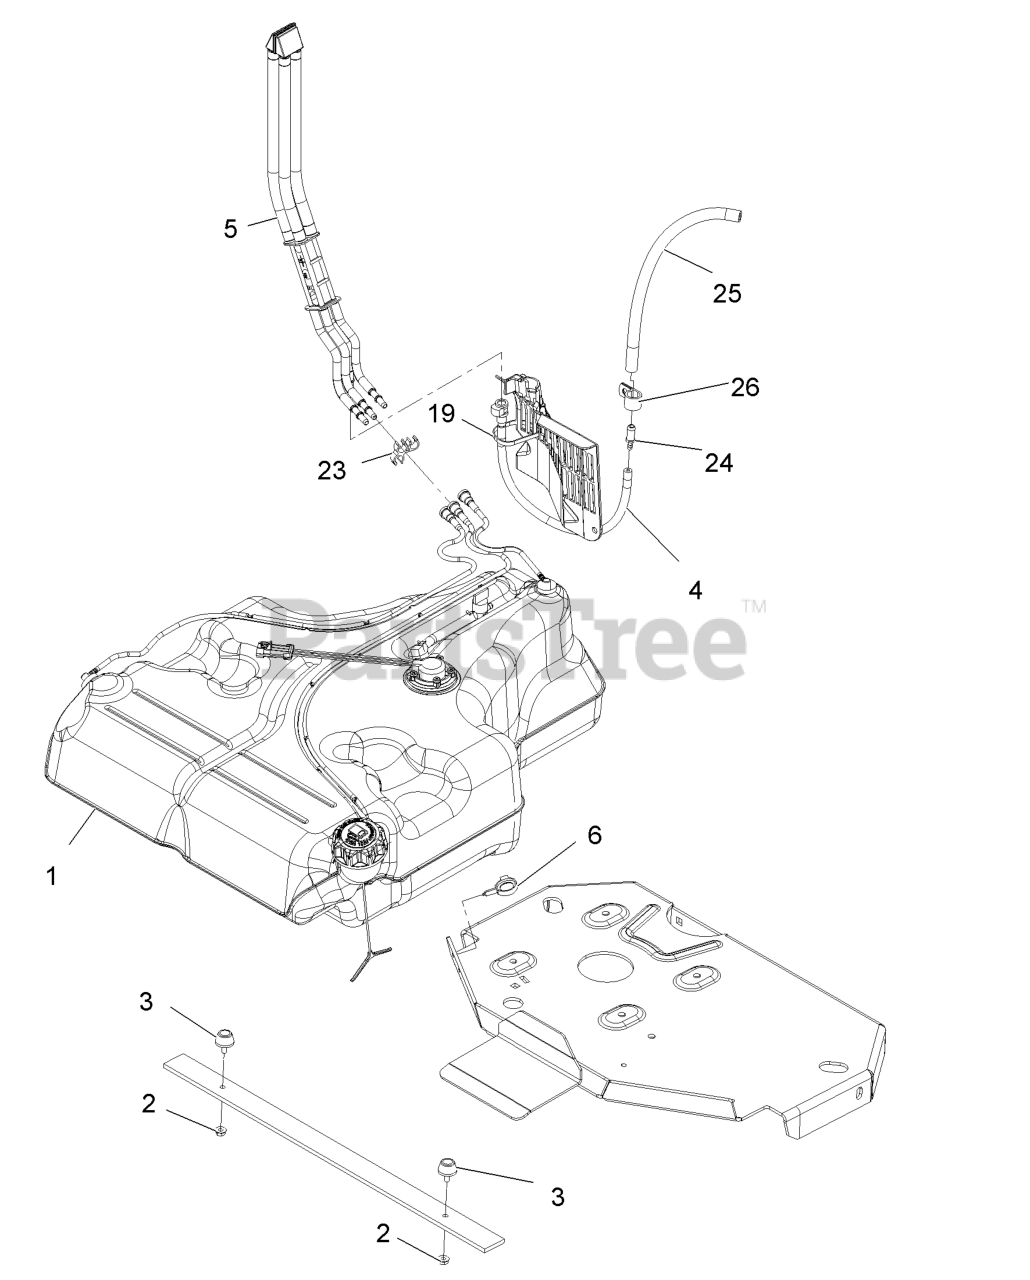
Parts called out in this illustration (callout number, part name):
3	BUMPER-RUBBER
4	HOSE ASM
5	FUEL MANIFOLD VENT ASM
6	CLAMP-HOSE
19	TIE-PLASTIC
23	CLIP-SPACER
24	FITTING-STRAIGHT
25	HOSE-FUEL
26	CLIP-LOOM
